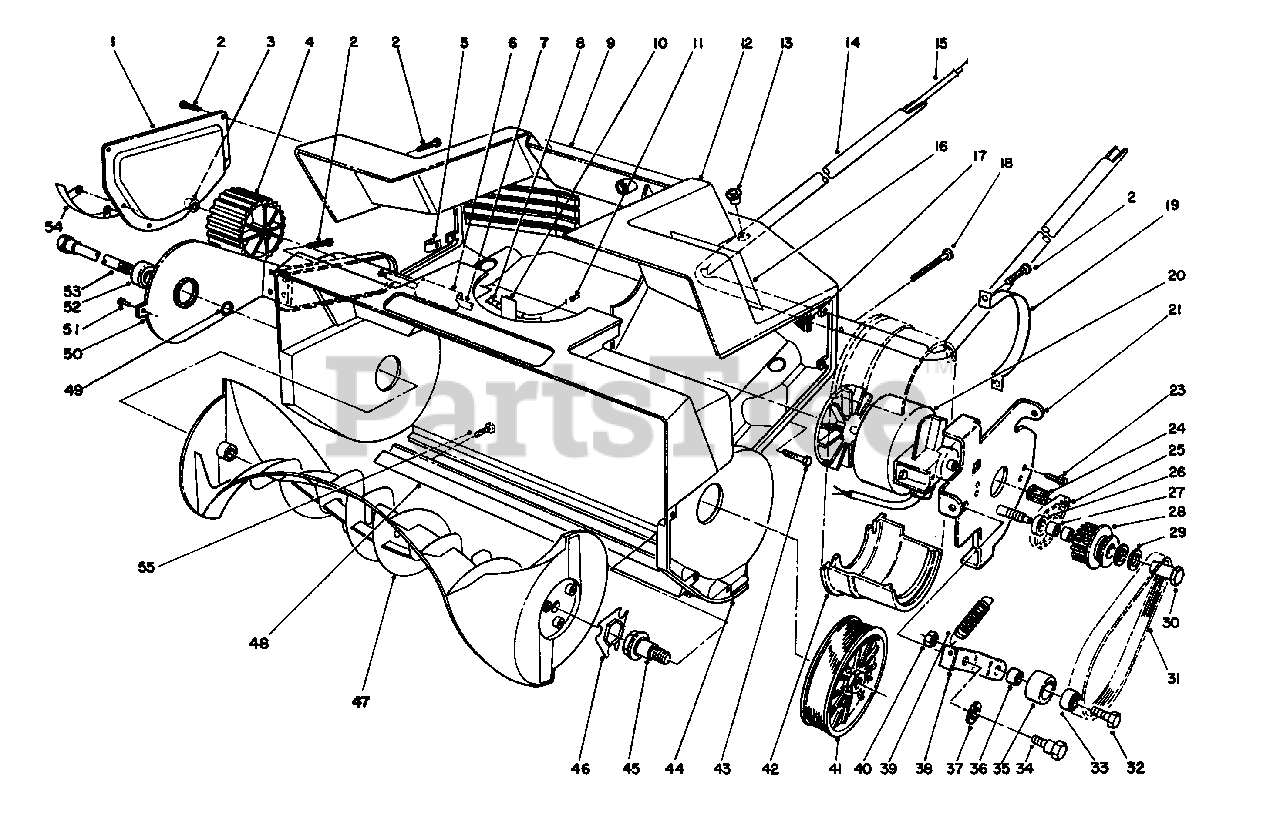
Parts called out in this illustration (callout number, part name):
1	Plate-Side
2	Screw-Pan Hd.
3	Push Nut
5	U-Clip-Tinnerman
6	Sleeve-Axle
7	Shaft-Axle
8	Relief-Strain
9	Decal-Danger Used on Machines Serial Nos. (1000101 Thru 1111100)
10	Clip-Cord Used on Machines Serial Nos. (1000101 Thru 1111100)
11	Connector
12	Shroud-Housing Used on Machines Serial Nos. (1000101 Thru 1111100)
14	Tube-Lower Handle
15	Wire Harness Used on Machines Serial Nos. (1100101 Thru 1111100 & 1200101 & UP)
16	Decal-Warning Used on Machines Serial Nos. (1000101 Thru 1111100)
17	Filter-Foam
18	Screw-Pan Hd.
19	Strap-Motor
20	Motor Used on Machines Serial Nos. (1000101 Thru 1111100)
21	Motor Plate Assembly
23	Screw-Hex. Washer Hd.
24	Pulley-Driver Used on Machines Serial Nos. (1000101 Thru 1111100)
25	Belt-Timing
27	Bearing-Needle
28	Pulley-Idler (Incl. Ref. #27)
29	Washer-Thrust
30	Bolt-Idler
31	Belt-Drive
32	Screw-Hex. Hd. Cap
33	Bearing-Ball
34	Screw-Shoulder
38	Bracket-Idler
40	Nut-Lock
41	Pulley-Driven
42	Clamp-Motor Bracket
43	Screw-Hex. Hd. Cap
44	Housing-Rotor Used on Machines Serial Nos. (1000101 Thru 1011100)
45	Shaft-Rotor Driver
46	Coupler-Rotor
47	Rotor
48	Scraper Used on Machines Serial Nos. (1100101 Thru 1111100 & 1200101 & UP)
50	Bracket-Wheel (Incl. Ref. #52)
51	Rivet-Pop
52	Bearing-Ball
53	Shaft-Rotor
54	Skid-Housing
55	Screw-Pan Hd. Used on Machines Serial Nos. (1100101 Thru 1111100 & 1200101 & UP)
